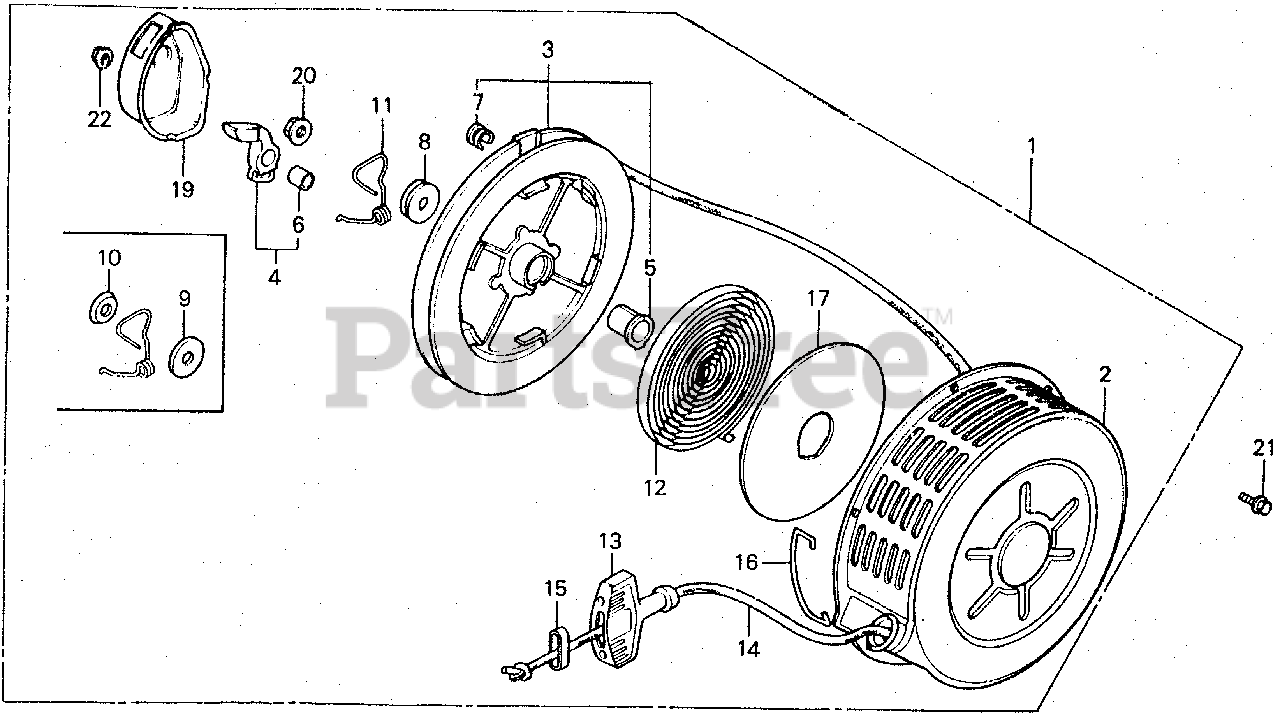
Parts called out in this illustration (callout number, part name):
1	STARTER ASSY., RECOIL *R8* (BRIGHT RED)
2	CASE, STARTER *R8* (BRIGHT RED)
3	REEL, STARTER
5	BOSS, REEL
6	BUSH, RATCHET
7	BUSH, REEL STARTER
9	PLATE, FRICTION
10	PLATE, FRICTION
11	SPRING, FRICTION
12	SPRING, RETURN
13	GRIP, STARTER
14	ROPE, STARTER (#6X64")
15	SUPPORT, GRIP
16	HOLDER, ROPE
17	PLATE, SIDE
19	COVER, REEL STARTER
20	NUT, SELF-LOCK (8MM)
21	BOLT-WASHER (6X10)
22	NUT, FLANGE (6MM)
